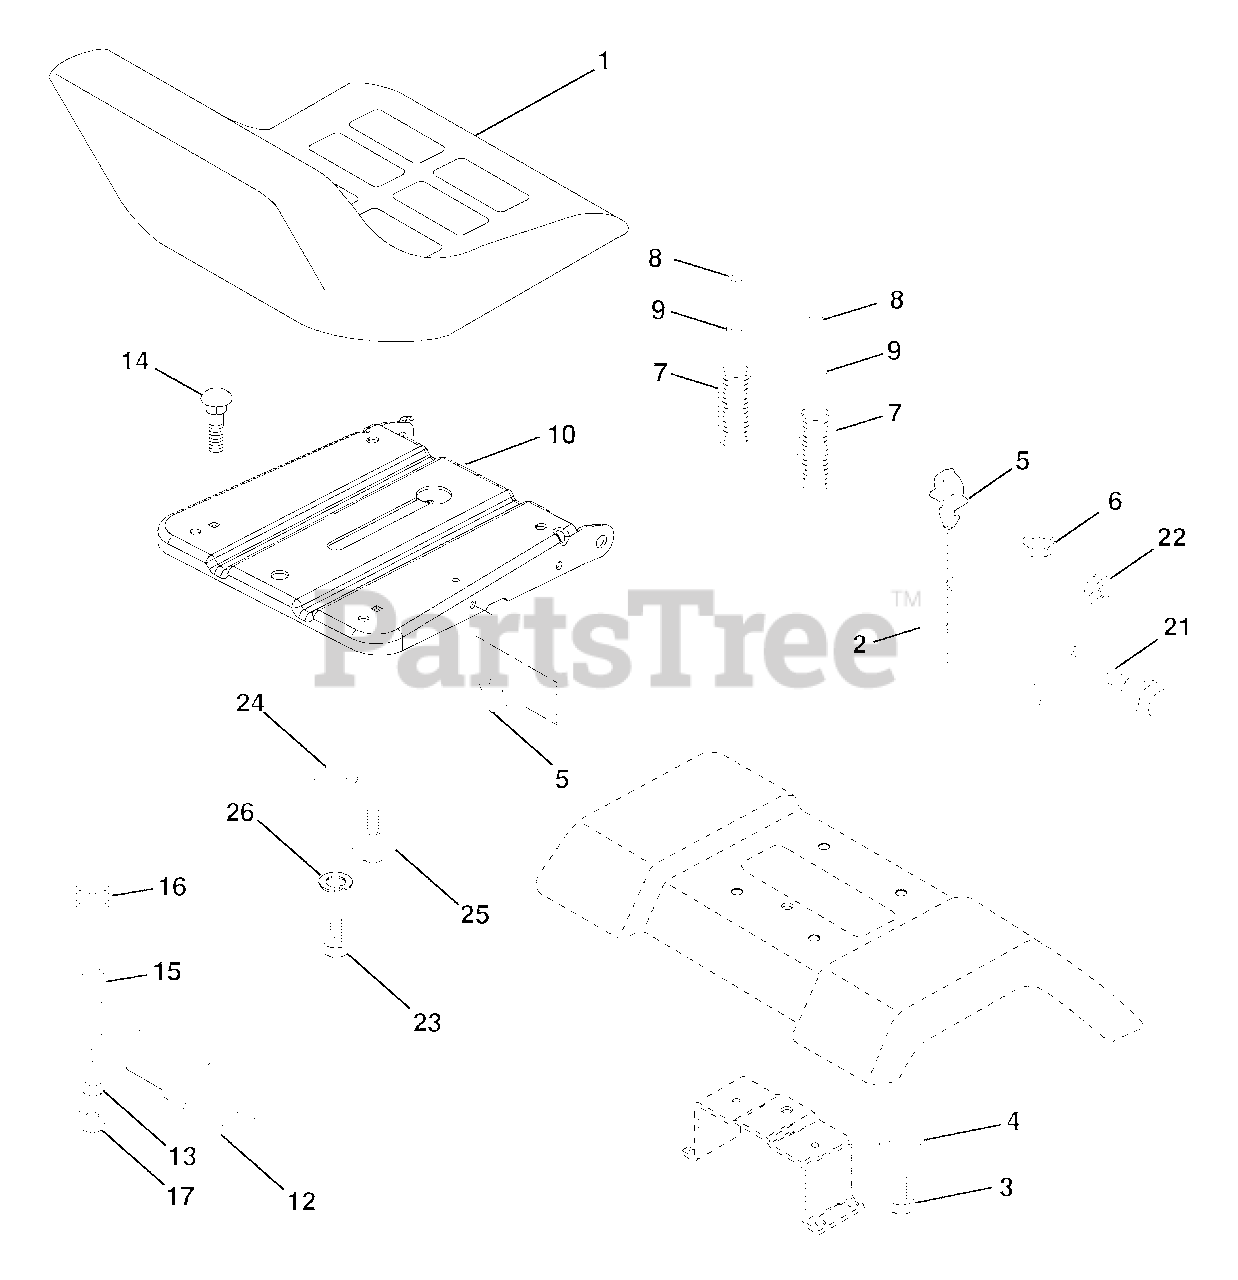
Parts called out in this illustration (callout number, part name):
1	Seat
2	Bracket Pnt Pivot Seat (blk)
3	Bolt
4	Washer 13/32 x 1 x 10 Ga.
5	Clip Push-In Hinged
6	Nut
7	Spring Seat Cprsn 2 250 Blk Zi
8	Screw 3/8-16 x 1.5
9	Washer 13/32 x 1 x 14 Ga.
10	Pan Pnt Seat (blk )
12	Bracket Pnt Mounting Switch
13	Bushing Snap Blk Nyl 50 Id
14	Bolt Rdhd Sht Nk 1/4-20 x 1-1/2
15	Spacer Split 28 x 96 Yel Zinc
16	Spring Cprsn 1 27 Blk Pnt
17	Nut Lock 1/4 Lge Flg Gr. 5 Zinc
21	Bolt Shoulder 5/16-18 unc Blkz-2A
22	Nut
23	Bolt Hex Black
24	Washer 17/32 x 1-3/16 x 12 Ga.
25	Bolt Shoulder 5/16-18 x 62
26	Lockwasher
